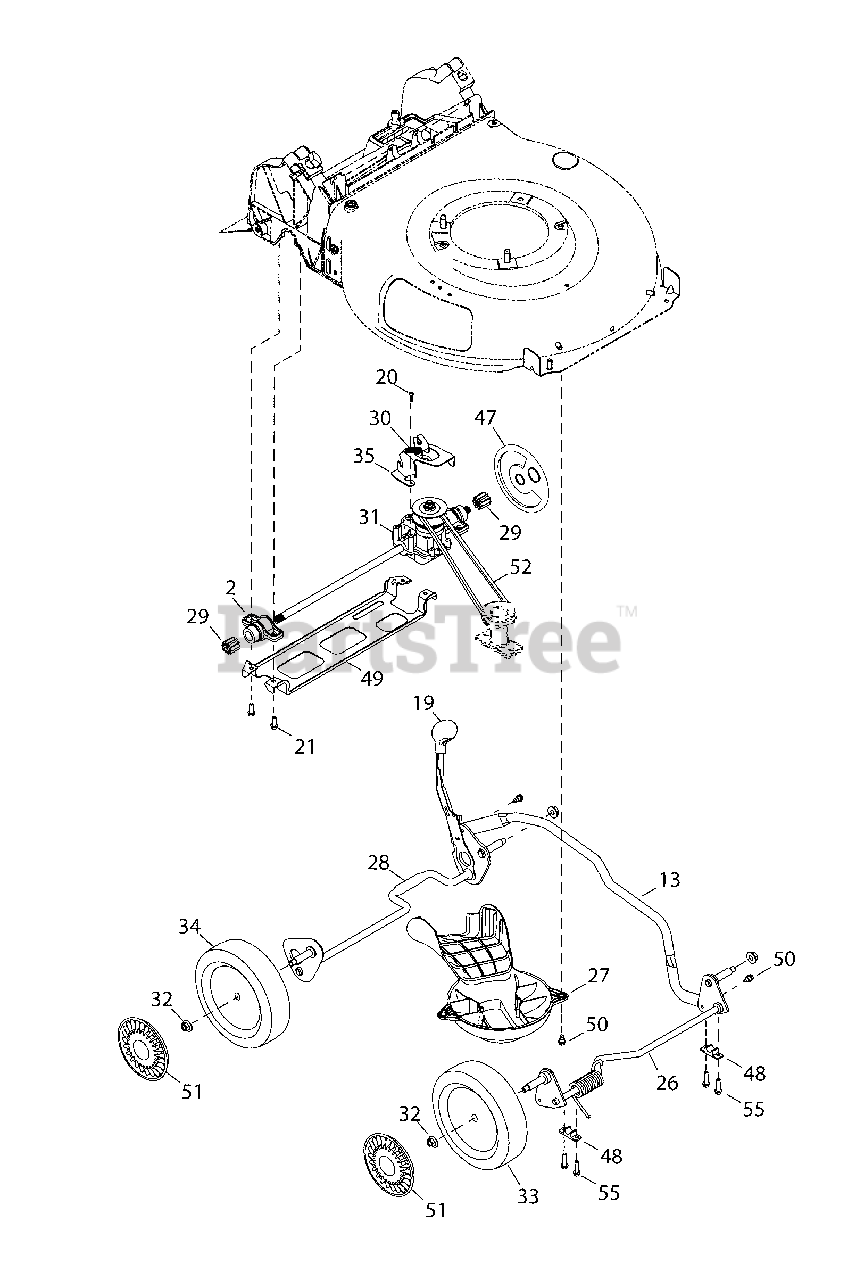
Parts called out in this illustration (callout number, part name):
2	BEARING
13	CROSS BRACKET
19	KNOB, Adjustment Lever
20	SCREW, Hex Washer Head, .159 x .43
21	SCREW, 1/4-15 x 1-1/4
26	* Engine, 14.5 Briggs Euro (w/oil filter)
27	BAFFLE, Engine
28	AXLE ASSEMBLY, Rear
29	GEAR, 10T
30	SPRING, Extension, 2.405
31	TRANSMISSION
32	NUT, Hex Flange, Nylock, 3/8-16
33	WHEEL, Front
34	WHEEL, Rear
35	BRACKET, Transmission
47	COVER, Dust
48	BUSHING, Lock, .505 Dia. X .62
49	BRACKET, Rear Support
50	BOLT, Shoulder, 1/4-20
51	HUBCAP, 8" Grey
52	V-BELT, 3L, 31.25"
55	SCREW, 1/4-15 x 1
